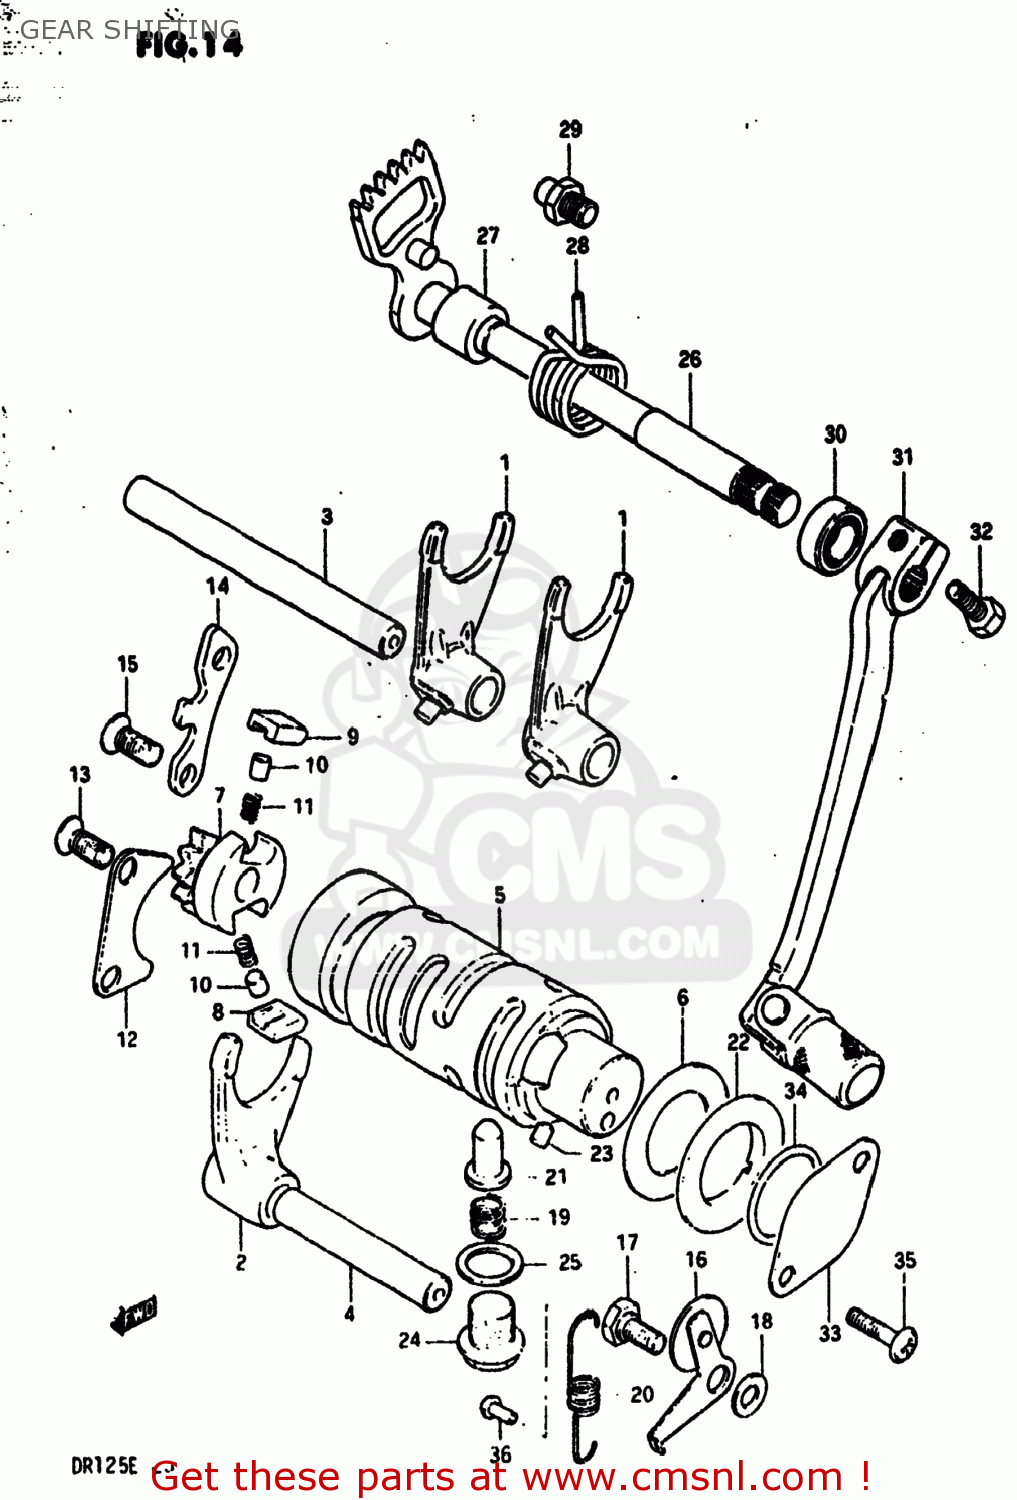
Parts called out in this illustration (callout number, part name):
1	FORK,GEAR SHIFT NO.1
2	FORK,GEAR SHIFT NO.3
3	SHAFT,GEAR SHIFT FORK
4	SHAFT,GEAR SHIFT FORK
5	CAM,GEAR SHIFT
6	WASHER,THRUST
7	SHIFTER,GEAR SHIFT CAM
8	PAWL,GEAR SHIFT NO.1
9	PAWL,GEAR SHIFT NO.2
10	PIN(5X8)
11	SPRING
12	LIFTER,GEAR SHIFT PAWL
13	SCREW
14	GUIDE,GEAR SHIFT CAM
15	SCREW
16	STOPPER,GEAR SHIFTING
17	BOLT
18	WASHER
19	SPRING
20	SPRING
21	STOPPER,GEAR SHIFT CAM NO.2
22	PLATE,GEAR SHIFT CAM STOPPER
23	PIN 4X6
24	PLUG (14X12)
25	GASKET(14X19.2X2) (NAS)
26	SHAFT,GEAR SHIFT
27	SPACER(12X20X15.3)
28	SPRING
29	STOPPER,GEAR SHIFT CAM
30	OIL SEAL
31	LEVER ASSEMBLY,GEAR SHIFTING
32	BOLT
33	CAP,GEAR SHIFT CAM PIVOT
34	O-RING (D:2.4 ID:26.2)
35	SCREW
36	RIVET
